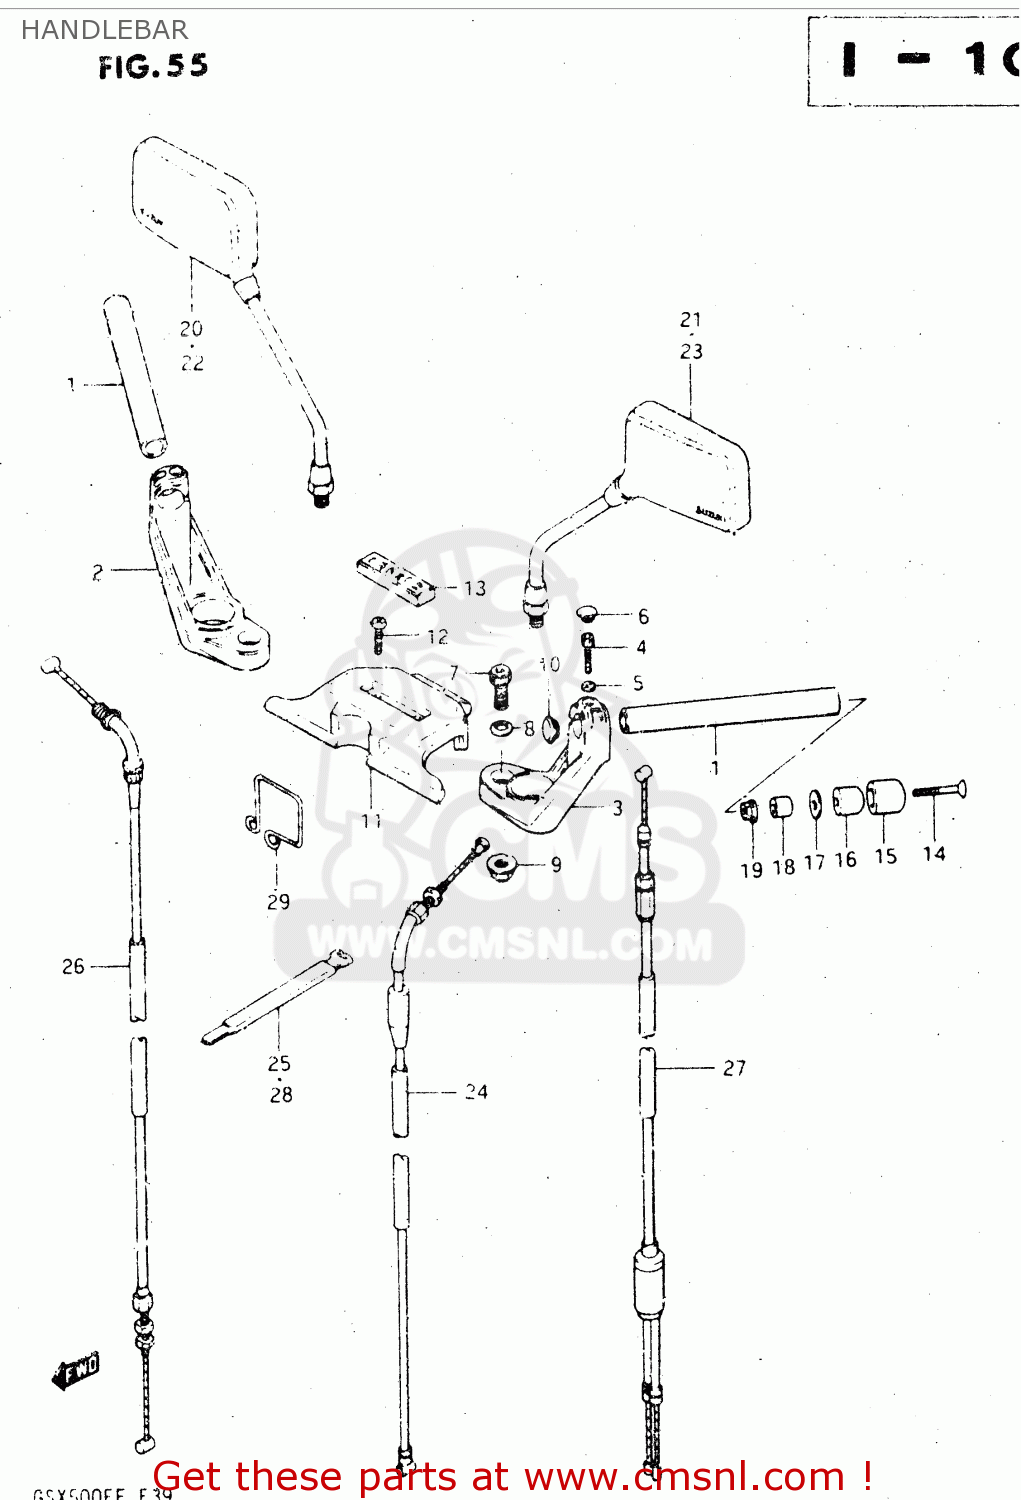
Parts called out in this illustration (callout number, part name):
1	HANDLEBAR
2	HOLDER,HANDLEBAR,RIGHT
3	HOLDER,HANDLEBAR,LEFT
4	BOLT 8X35
5	WASHER
6	CAP(OD:14.5)
7	BOLT(10X50)
8	WASHER
9	NUT
10	CAP,GRIP END
11	PAD,HANDLEBAR
12	SCREW
13	EMBLEM,HANDLE PAD
14	SCREW 6X55
15	CAP,BALANCER
16	BALANCER,HANDLEBAR
17	SPACER,BALANCER
18	EXPANDER,BALANCER
19	NUT
20	MIRROR, REAR VIEW RH
21	MIRROR, REAR VIEW LH
22	MIRROR ASSEMBLY,REAR VIEW
23	MIRROR ASSEMBLY,REAR VIEW
24	CABLE ASSY,CLUTCH
25	CLAMP
26	CABLE ASSY,THROTTLE
27	CABLE COMP,STARTER
28	CLAMP
29	GUIDE,CABLE/HARNESS
